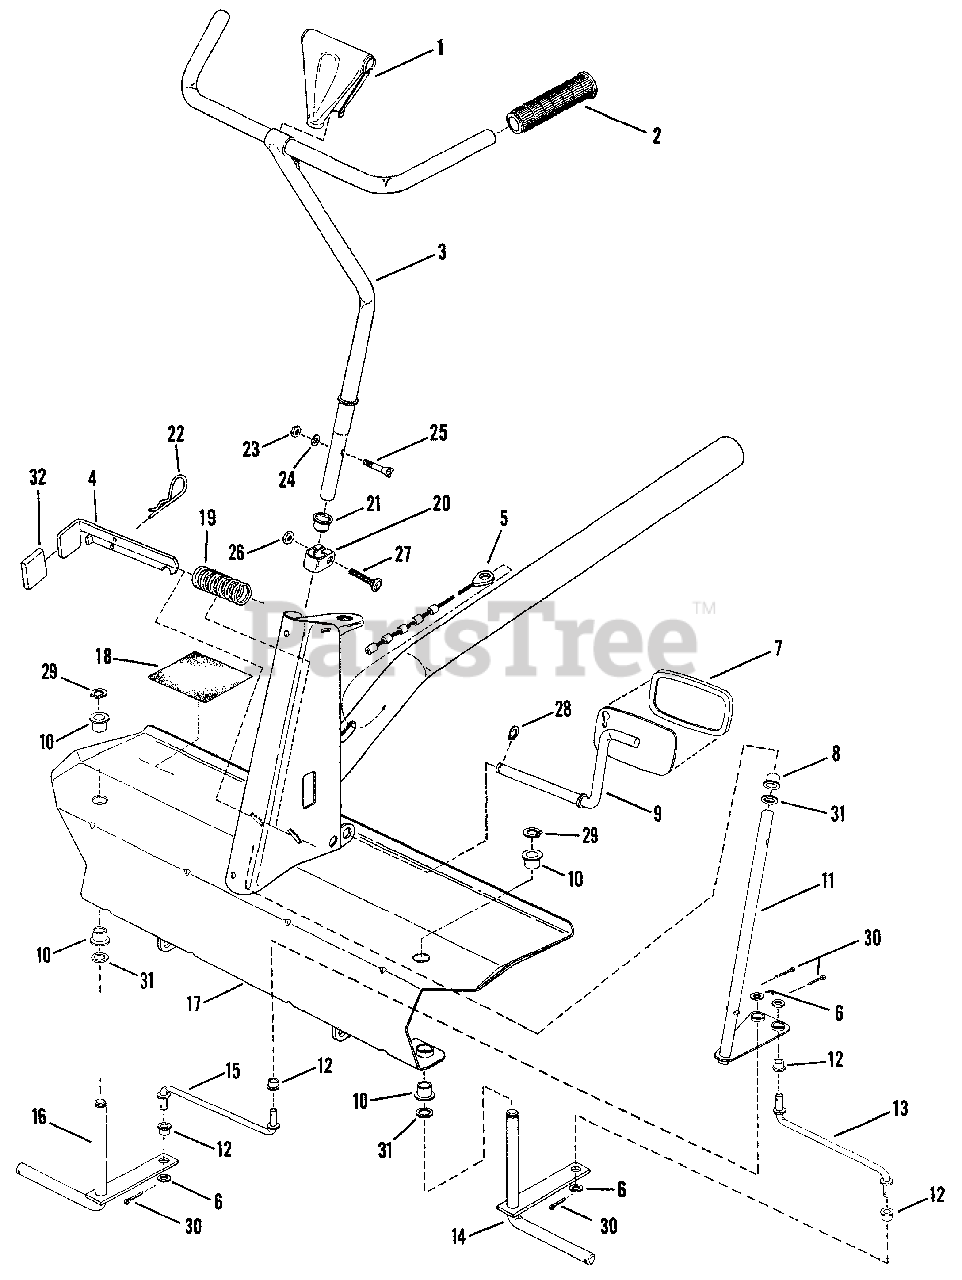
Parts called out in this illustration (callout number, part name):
1	COVER, Handle
2	GRIP, Handle
3	HANDLE, Steering
4	Latch, Parking Brake
5	CABLE, Clutch/Brake (46.1" Yellow)
6	WASHER, 3/8" Flat
7	PAD, Clutch/Brake Pedal
8	BUSHING, Nylon
9	PEDAL, Clutch/Brake
10	BEARING
11	SHAFT, Steering
12	BUSHING, Tie-Rod
13	TIE-ROD, Left Hand
14	King Pin, L.H.
15	TIE-ROD, Right Hand
16	King Pin, R.H.
17	FRONT AXLE STRUCTURE (Narrow)
18	PAD, Foot
19	SPRING, Parking Brake
20	CLAMP, Steering
21	BUSHING, Nylon
22	PIN, Hair
23	NUT, 1/4-28 Hex
24	WASHER, 1/4 Internal Tooth Lock
25	BOLT, 1/4-28 Tapered Head
26	NUT, 5/16-18 Hex
27	BOLT, 5/16-18x1 1/2" Carriage
28	RING, Retaining
29	RING, Retaining
30	COTTER-PIN, 1/8x3/4
31	WASHER, 5/8 Flat
32	CAP, Parking Brake Lever
